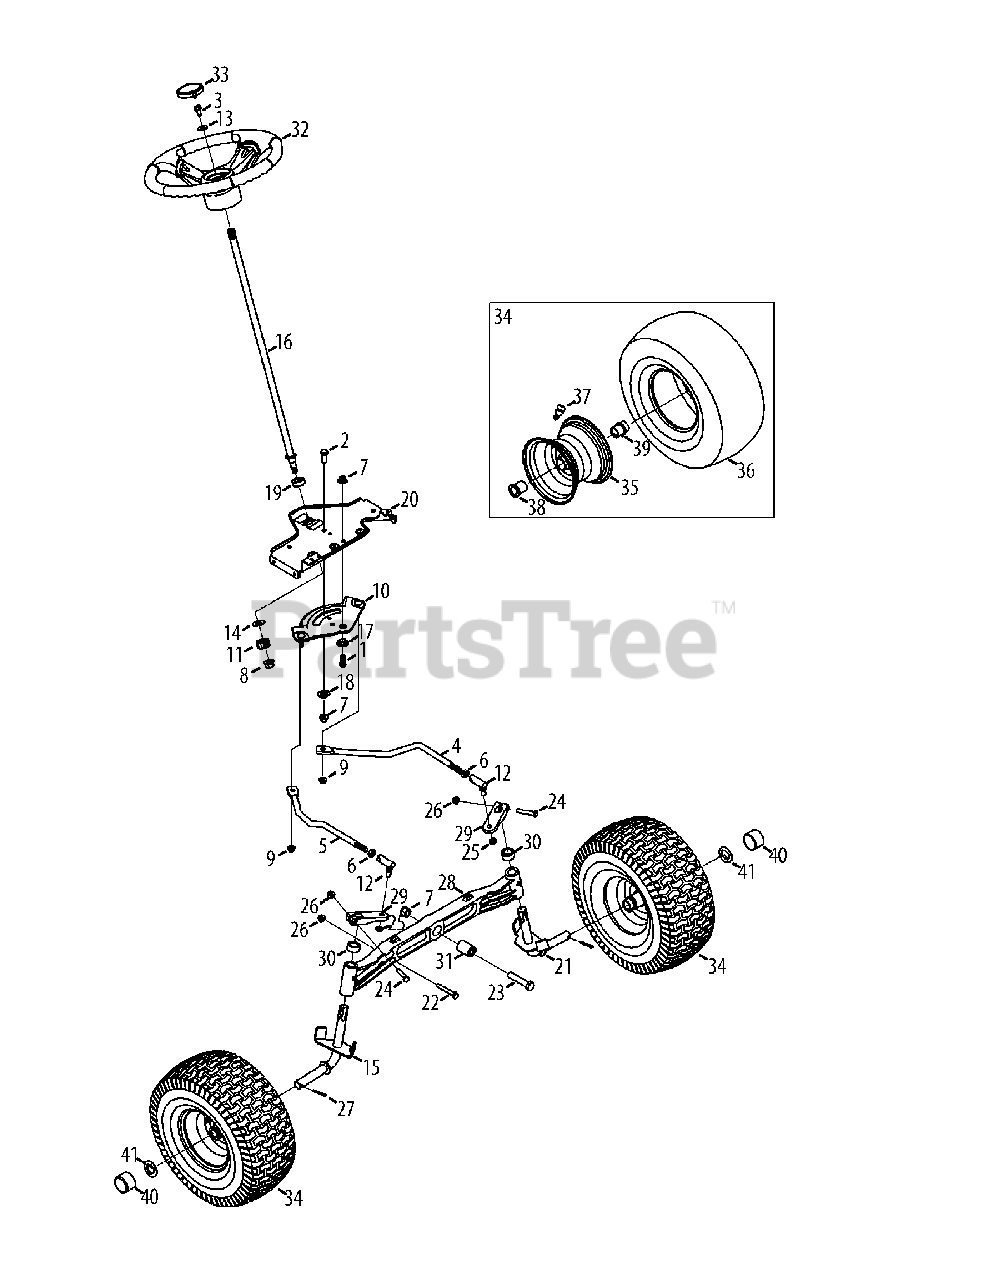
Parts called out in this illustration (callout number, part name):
1	Hex Head Screw, 3/8-16:1.00
2	Hex Head Screw, 3/8-16:1.00
3	Hex Head Screw, 5/16-18:1.00
4	LH Drag Link
5	RH Drag Link
6	Jam Nut, 7/16-20
7	Flangelock Nut, 3/8-16
8	Flangelock Nut, 7/16-20
9	Flangelock Nut, 5/16-18
10	Steering Gear
11	Steering Pinion Gear
12	Ball Joint, 7/16-20
13	Flat Washer, .406 x .875 x .105
14	Flat Washer, .51 x 1.12 x .06
15	RH Axle Assembly
16	Steering Shaft, .625 OD x 24.25 LG
17	Shoulder Spacer, .385 x 1.25 x .3025
18	Spacer, .38 x 1.375
19	Hex Flange Bearing 5/8 PM
20	Steering Support Bracket
20	Screw, .750 5/16-18
21	LH Axle Assembly
22	Hex Head Screw, 5/16-18:2.25
23	Hex Head Screw, 3/8-16:2.50
24	Hex Head Screw, 5/16-18:1.75
25	Hexlock Nut, 3/8-24
26	Flangelock Nut, 5/16-18
27	Cotter Pin, 5/32:1.25
28	Pivot Bar Axle
29	Steering Block
30	Spacer, .71 ID x .125 OD x .56LG
31	Spacer, .385 x 1.00 x 1.5075
32	Steering Wheel, Standard Grip
33	Steering Wheel Cap, Sprig
34	Wheel Assembly
35	Rim Assembly
37	Tubeless Air Valve
38	Flange Bearing, .760 x 1.00 x 1.20LG
39	Flange Bearing, .760ID
40	Bumper Cap
41	Flat Washer, .781ID x 1.590OD
